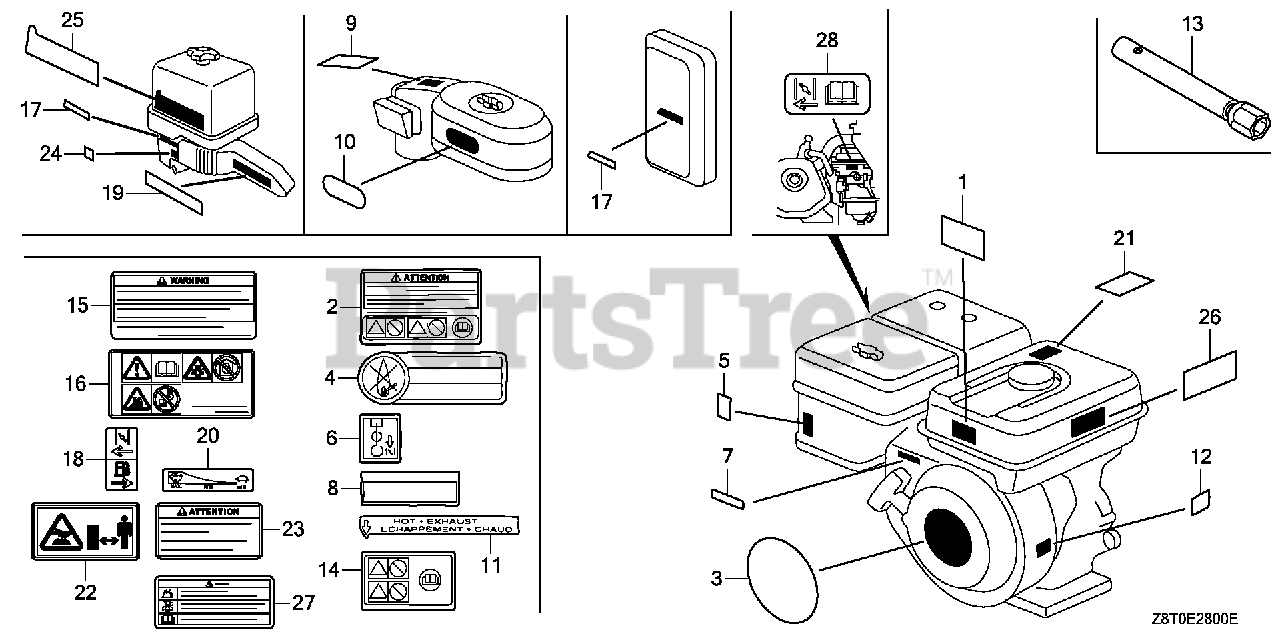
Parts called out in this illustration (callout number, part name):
3	EMBLEM (GX340)
13	WRENCH, SPARK PLUG
15	MARK, OPERATOR CAUTION (ENGLISH)(MADE IN THAI)
15	MARK, OPERATOR CAUTION (FRENCH)(MADE IN THAI)
16	MARK, OPERATOR CAUTION (PICTOGRAPH)
18	MARK, CHOKE
20	MARK, THROTTLE INDICATION
21	MARK, EX. CAUTION (ENGLISH)
22	MARK, EX. CAUTION (PICTOGRAPH)
23	MARK, EX. CAUTION (FRENCH)
